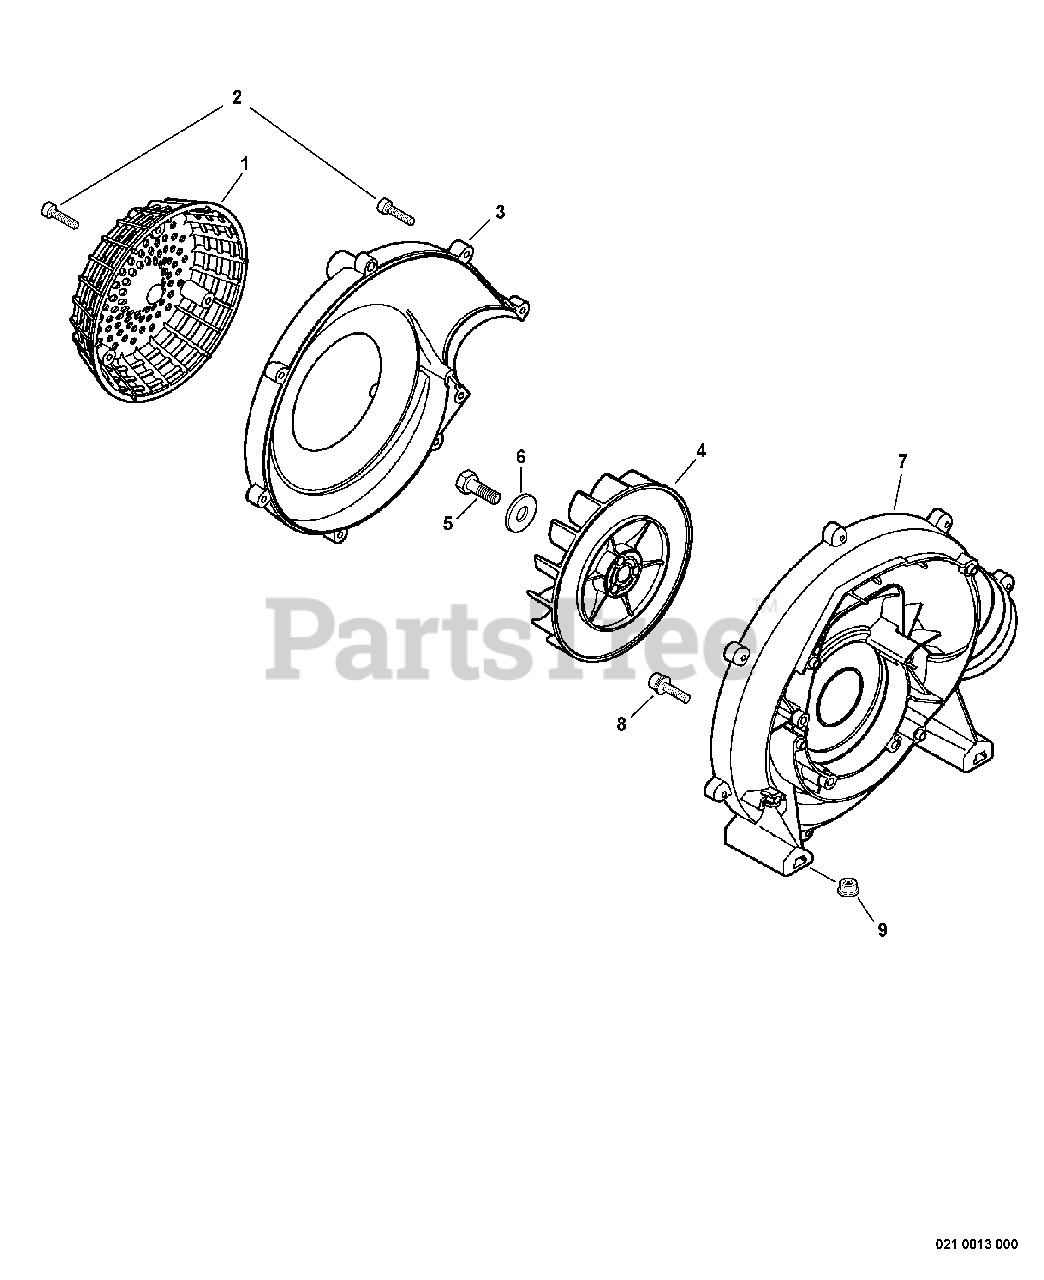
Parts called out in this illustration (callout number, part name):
1	GUARD, DEBRIS
2	SCREW - 5X20 -- TAPPING
3	COVER, FAN - LEFT
4	FAN
5	BOLT - 8X14
6	WASHER - CUP
7	COVER, FAN - RIGHT
8	SCREW - 4X20
9	NUT - 5 -- FLANGE
